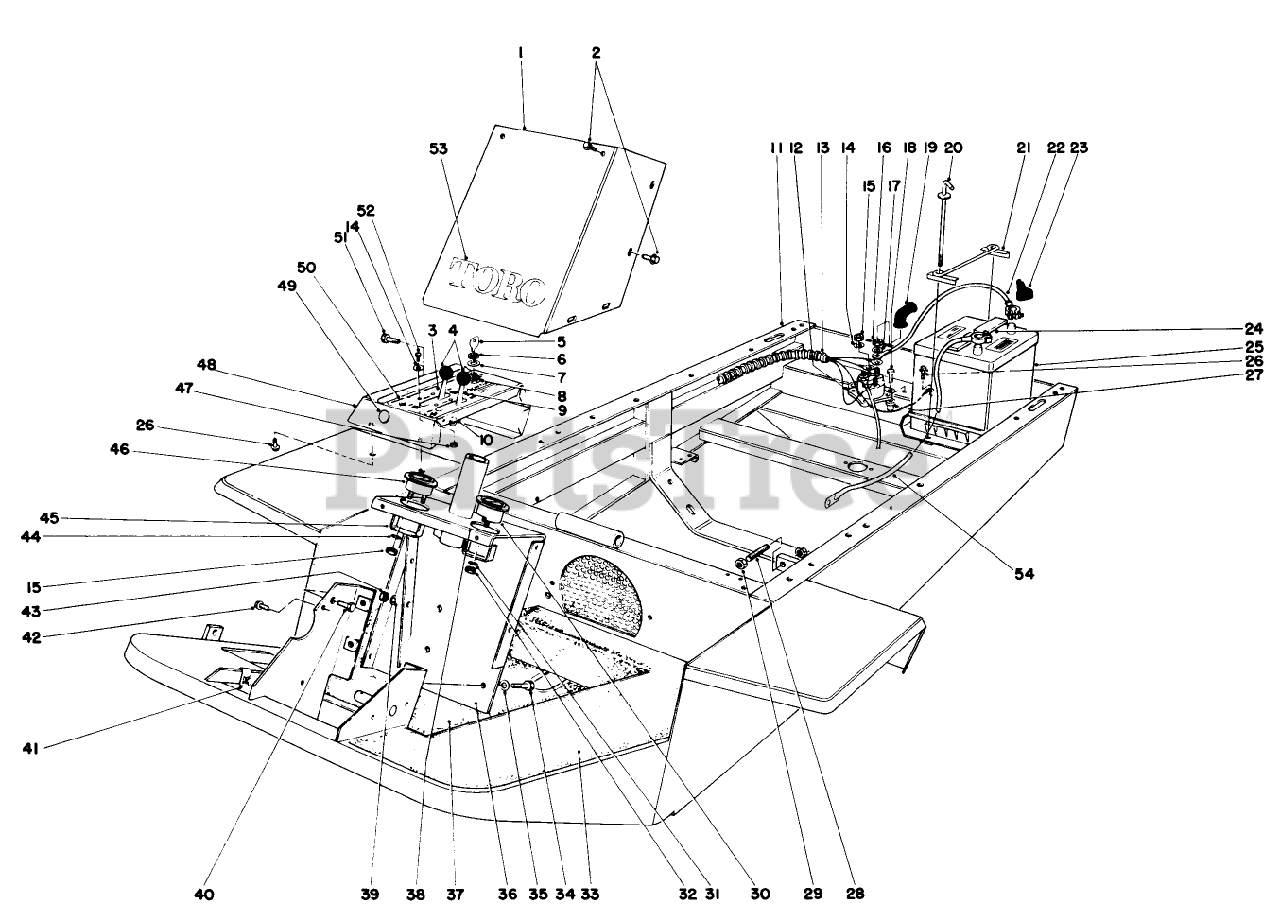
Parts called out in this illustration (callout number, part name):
1	Tower Cover
2	SCREW-HHFTF
3	CHOKE CONTROL
5	Key
6	NUT-HH
7	WASHER-TOOTH, INTERNAL
8	Starter Switch (Incl. Ref. #5-7)
9	THROTTLE CONTROL
10	WASHER-FLAT
11	Frame
12	SOLENOID
13	WIRE HARNESS
14	WASHER-LOCK
15	NUT-HEX
16	NUT-JAM, BRASS
17	WASHER-LOCK
18	SCREW-HH
19	BATTERY BOOT
20	BATTERY BOLT WA B
21	BATTERY HOLD DOWN WA
22	BATT/SOLENOID WIRE
23	BOOT-CABLE, BATTERY
24	PUSH-ON BATTERY CAP
25	Battery
26	SCREW-THD FRM,HWH
27	NUT-INSERT
28	STOP PIN PP
29	NUT-JAM
30	HOUR METER
31	WASHER-LOCK, INT
32	NUT-HEX
33	NON SKID (TUNNEL)
34	SCREW-HH
35	WASHER-LOCK
36	Steering Post
37	NON-SKID-FLOOR
38	INSTRUCTION DECAL
39	WASHER-LOCK
40	SCREW-HH
41	SPEED NUT
42	SCREW-HWH
43	NUT-HEX
44	WASHER-FLAT
45	MTG CLAMP F/W GUAGE
46	AMMETER GAUGE ASSY
47	NUT-HEX
48	Instrument Panel
49	Domed Plug
50	Decal-Instrument Panel
51	SCREW-HH
52	10-24 X 5/8 PAN HD MS
53	DECAL
54	BATTERY GROUND WIRE
